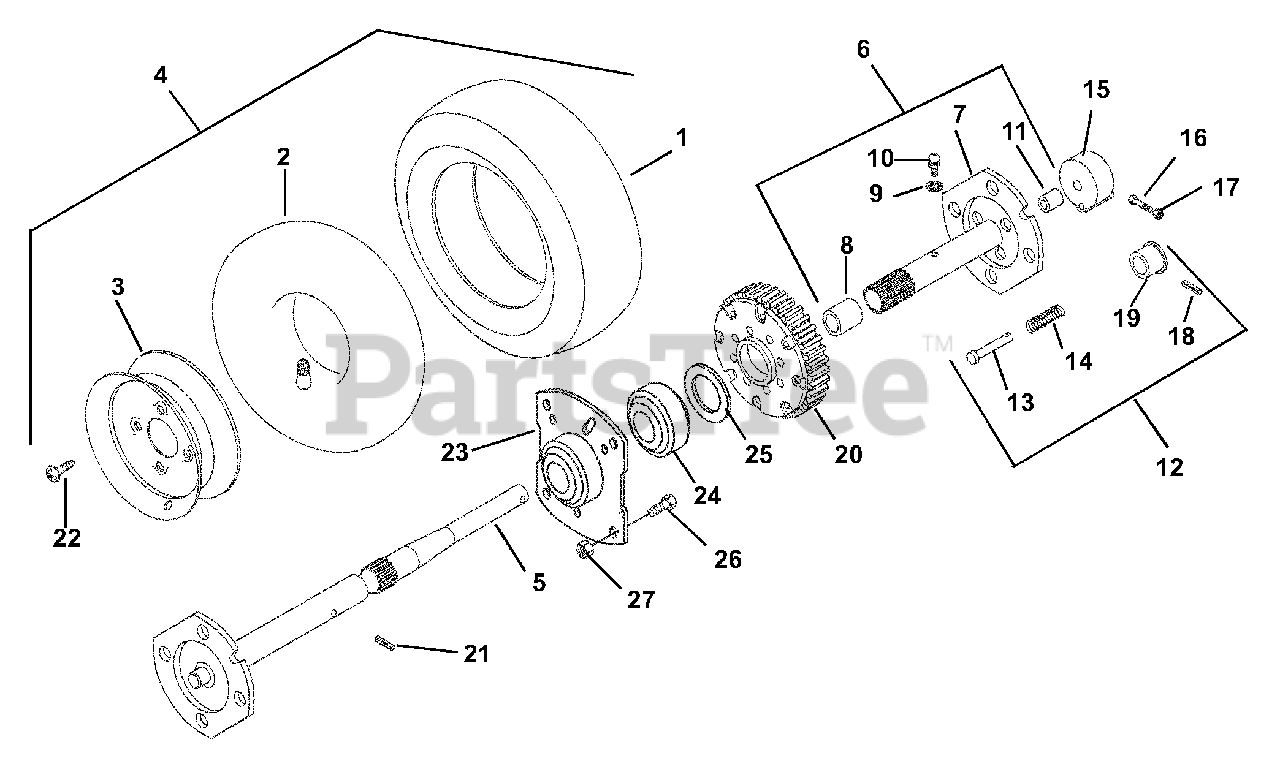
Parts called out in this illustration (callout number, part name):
1	Tire 16 x 6.50-8
2	Tube 6.50 x 8
3	Wheel 6.50-8
4	Tire/Wheel Assembly 16 x 6.50-8
5	Axle, Right Hand
6	Axle Assembly Left Hand
7	Axle, Left Hand
8	Bushing, Sleeve .75 x .81 x .75
9	Washer, Locking .25 x .05
10	Fitting, Lube .25-28 x .26
11	Bushing, Sleeve .56 x .63 x .63
12	Lockout Hub Assembly
14	Spring, Compression .03 x.34 x 1.06
15	Lockout Hub
16	Screw, Cap .25-20 x 2.00 Grade 8
17	Nut, Jam Nylon .25-20
18	Pin, Roll .09 x 1.00
20	Differential Assembly
21	Pin Roll .19 x 1.50
22	Screw, Tapping .50-20 x .62 Hex Head
23	Bearing Retainer
24	Bearing, Ball 1.13 x 2.19 x .63
25	Washer, Flat Steel 1.14 x 1.72 x .13
26	Bolt Serrated Neck Slotted .25-20 x .50
27	Nut, Locking Flange .25-20
